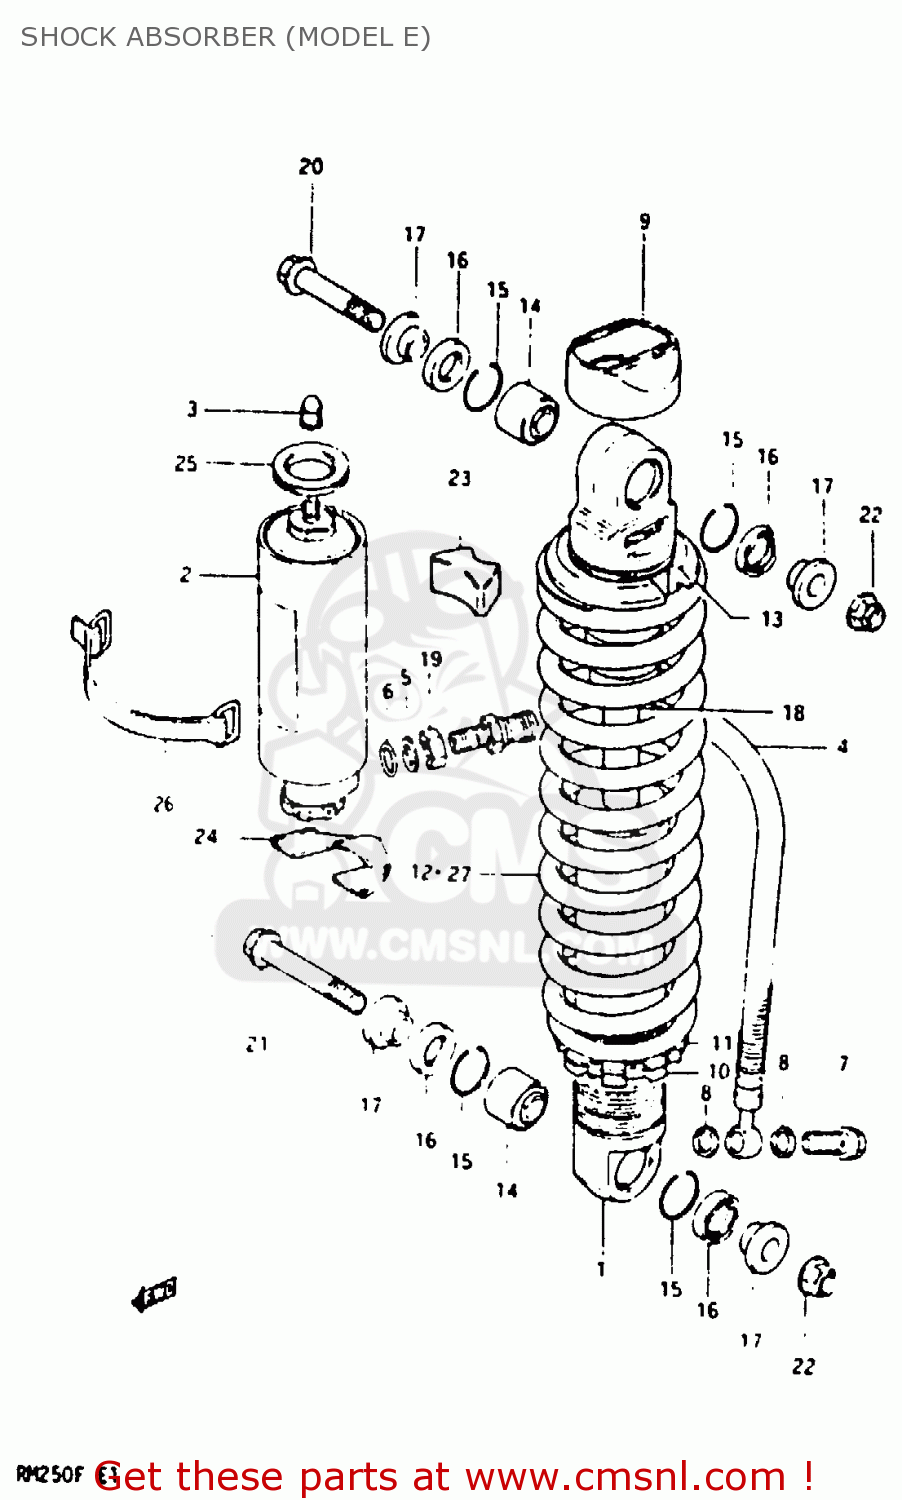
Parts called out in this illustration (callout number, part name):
1	ABSORBER ASSEMBLY,REAR SHOCK
2	RESERVE TANK,REAR SHOCK
3	CAP
4	HOSE,REAR SHOCK ABSORBER
5	WASHER,REAR SHOCK HOSE
6	O-RING,RESERVE TANK
7	BOLT,REAR SHOCK ABSORBER
8	GASKET (NAS)
9	CAP
10	GUIDE,REAR SHOCK ABSORBER SPRING
11	GUIDE,SPRING
12	SPRING,REAR SHOCK
13	GUIDE,REAR SHOCK ABSORBER SPRING
14	BEARING,REAR SHOCK ABSORBER
15	RING
16	SEAL,DUST
17	SPACER
18	ROD,PISTON
19	NUT 12MM
20	BOLT,REAR SHOCK ABSORBER
21	BOLT(10X52)
22	NUT
23	CUSHION,RESERVOIR TANK
24	CUSHION,RESERVOIR TANK
25	CUSHION,RESERVOIR TANK
26	BAND
27	SPRING
